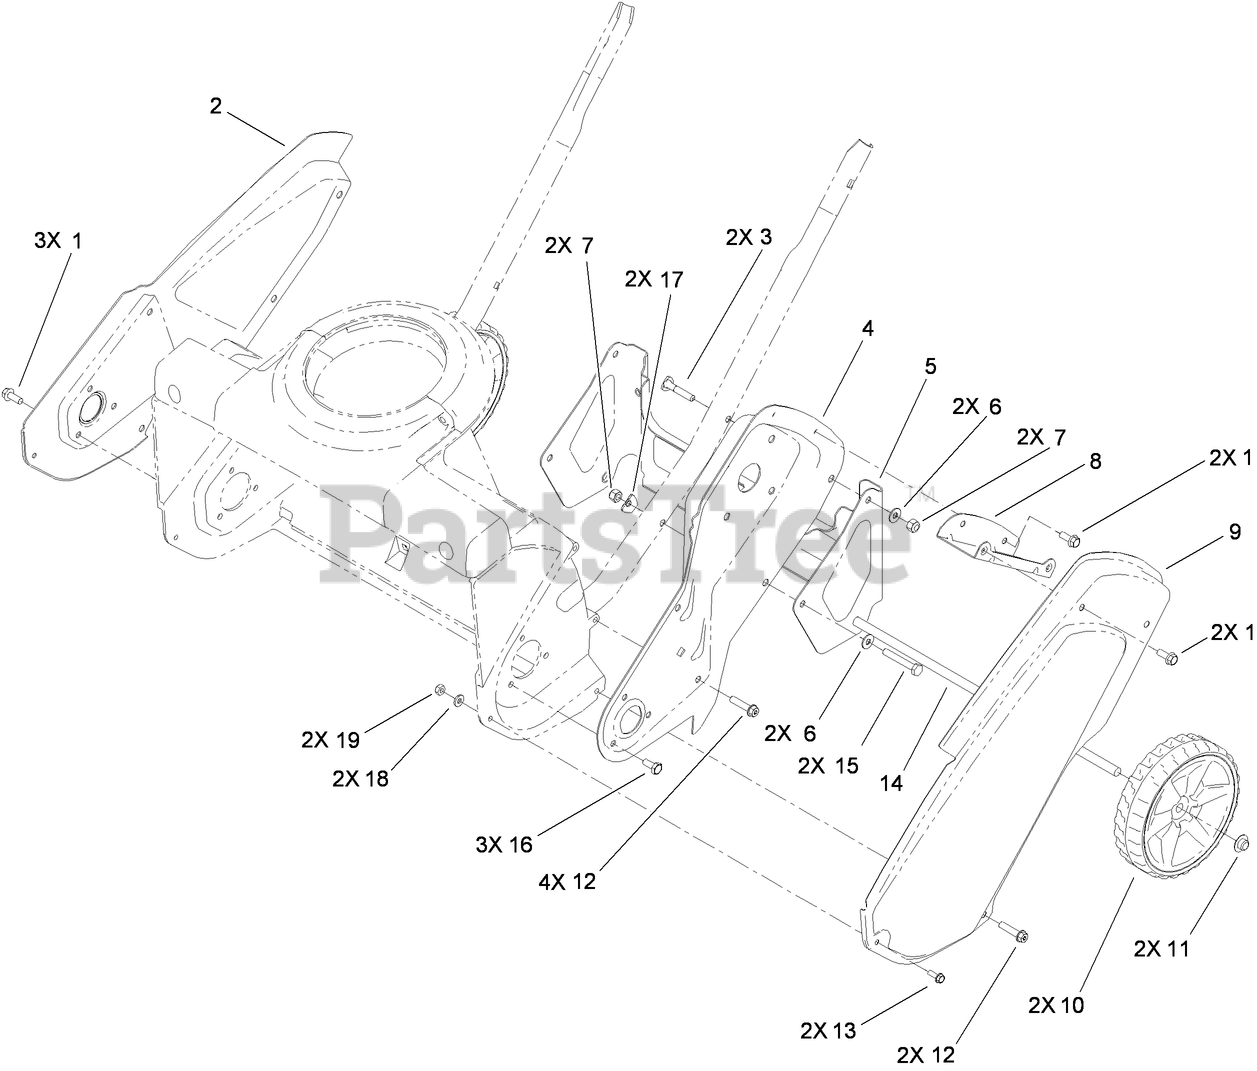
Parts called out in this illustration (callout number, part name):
1	SCREW-HWH
2	SIDEPLATE-RH
3	SCREW-HANDLE
4	SIDEPLATE-LH
5	BRACKET-WHEEL
6	WASHER-FLAT
7	NUT-LOCK, NI
8	BRACKET-COVER, BELT
9	COVER-BELT
10	WHEEL
11	NUT-PUSH
12	SCREW-PLASTIC
15	SCREW-HH
16	SCREW-HH, TAPTITE
17	WASHER
18	WASHER-FLAT
19	NUT-LOCK, NI
